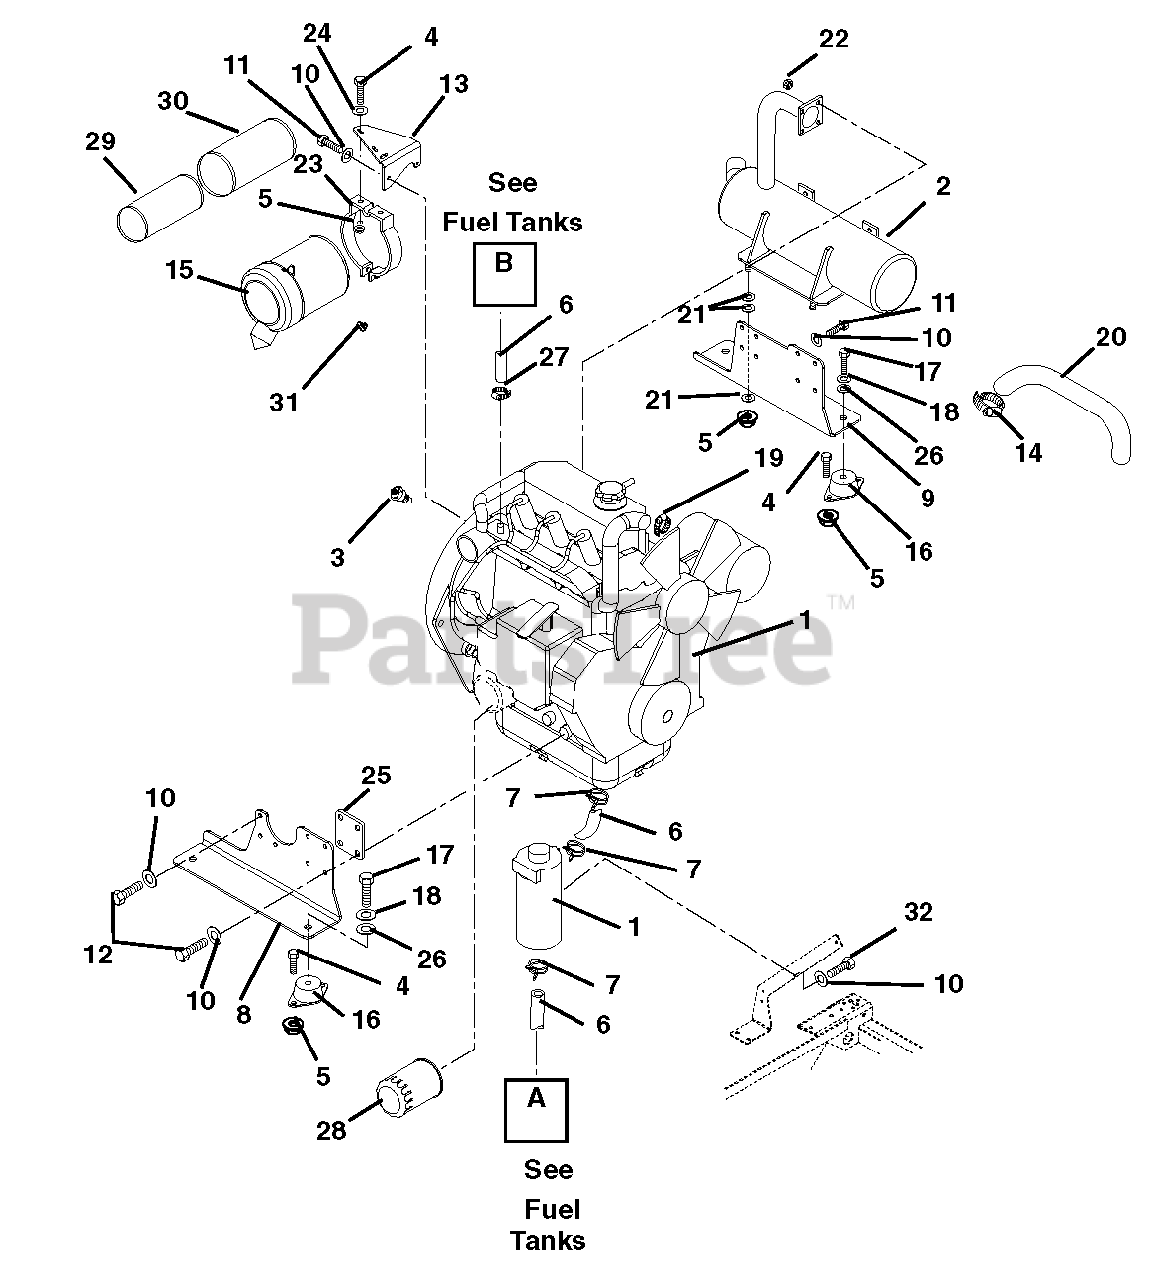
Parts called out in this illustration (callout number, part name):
1	Engine, 27HP Daihatsu Diesel (950D) (195)
2	Muffler (195)
3	Sender, Temperature
4	Bolt, Hex .31-18 x .75 Grade 5
5	Nut, Locking Top Flange .31-18
6	Gas Line, Bulk .31" ID
7	Hose, Clamp
8	Mount, Engine Right Hand
9	Mount, Engine Left Hand
10	Washer, Lock .31 x .078 Regular
11	Bolt, Hex M8-1.25 x 20
12	Bolt, Hex M8 x 1.25 x 25 Grade 8
13	Bracket, Air Cleaner
14	Clamp, 2.50" Dia. Hose
15	Assembly, Air Cleaner
16	Mount, Engine
17	Bolt, Hex .50-20 x 1.00 Grade 5
18	Washer, Locking .50 x .125 Regular
19	Clamp, Hose 1.50 x .81 x 1.42
20	Hose, Air Cleaner (195)
21	Washer, Flat Steel .38 x .875 x .083
22	Nut, Locking, Top M8-1.25
23	Bracket, Air Cleaner Mount
24	Washer, Flat Steel .38 x .875 x .083
25	Spacer, Engine Mounting
26	Washer, Flat Steel .531 x 1.06 x .095
27	Hose Clamp
28	Oil Filter
29	Element, Inner Safety
30	Element, Outer Primary
31	Plug, Pipe .125-27
32	Bolt, Hex M6-1 x 16
